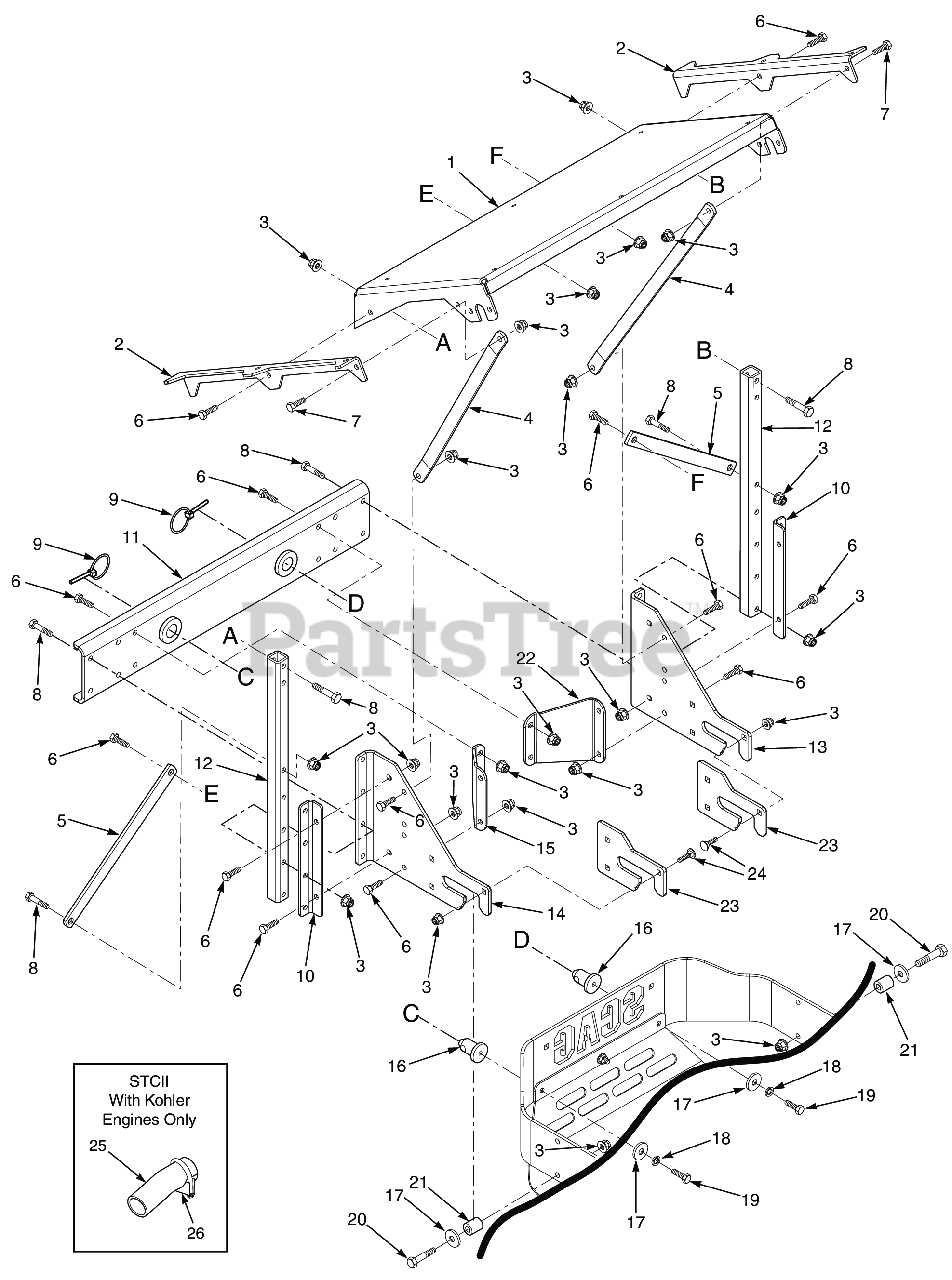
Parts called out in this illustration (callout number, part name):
1	Support Frame, Hopper
2	Bracket, Hopper Support
3	Nut, Flange Elastic Stop Nut, 3/8-16
4	Brace, Stiffener
5	Brace, Engine Mounting
6	Bolt, Hex Head, 3/8-16 x 1 Gr. 5
7	Bolt, Hex Head 3/8-16 x 1-1/4", Kawasaki FX / FS
8	Bolt, Hex Head 3/8-16 x 2-1/4" - 61"
9	Quick Pin, 5/16" Dia.
10	Mounting Bracket, Tube
11	Mounting Bracket Weldment
12	Tube, Upright
13	Mounting Bracket, GC R.H.
14	Mounting Bracket, GC L.H.
15	Angle Bracket, GC
16	Pin, GC Locator
17	Flatwasher, 3/8-.406 x 1-1-1/2 x 7 Gauge
18	Lockwasher, 3/8" Spring, Kawasaki FX / FS
19	Bolt, Hex Head 3/8-16 x 1-1/4", Kawasaki FX / FS
20	Bolt, Hex Head 3/8-16 x 2-1/4" - 61"
21	Spacer
22	Angle Bracket, GC
23	Wear Plate, GC
24	Carriage Bolt, 3/8-16 x 1-1/4"
25	TUBE, EXHAUST
26	Clamp, Muffler (Clamp Only)
